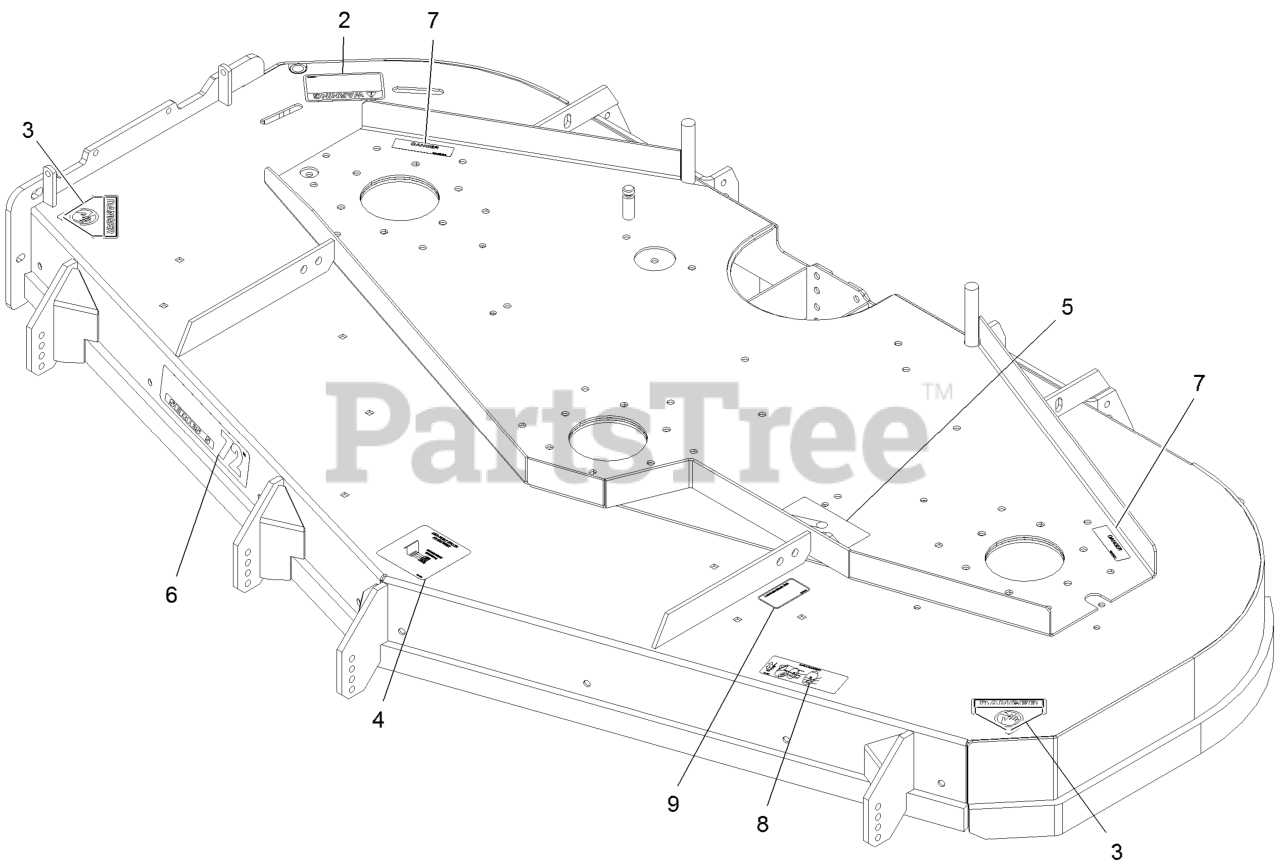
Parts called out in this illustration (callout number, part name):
2	DECAL-WARNING, DISCHARGE
3	DECAL-DANGER
4	DECAL,ANTISCALP
5	DECAL,BELT ROUTING
6	DECAL, SERIES 5 - 72
7	DECAL-COVER, MISSING
8	DECAL,BAFFLE ADJUSTMENT
9	DECAL,BOLT TORQUE
